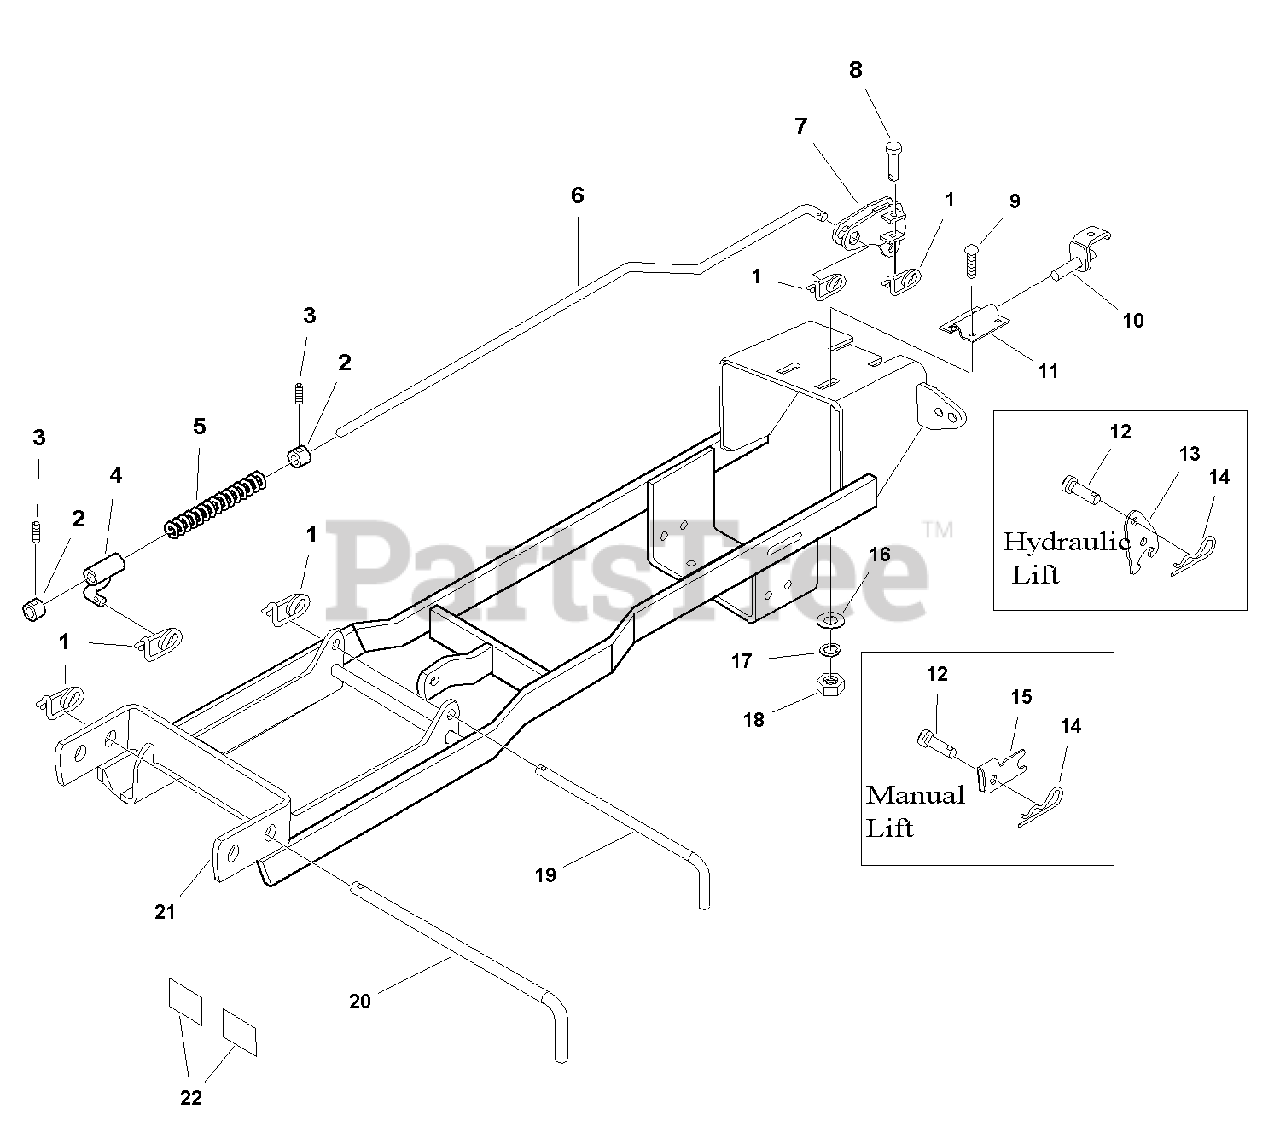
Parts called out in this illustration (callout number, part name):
1	RETAINER, Pin
2	COLLAR, Set
3	SCREW, Set, Square Head, Cup Point, 5/16-18 x 1/2, GR 8
4	TUBE & PIN ASSEMBLY
5	SPRING, Compression
6	ROD, Rear Lift
7	LEVER ASSEMBLY
8	PIN, Round Head,3/8 x 2-3/8
9	CARRIAGE BOLT, 5/16-18 x 1
10	SHAFT & HOOK ASSEMBLY
11	CLAMP, Wheel Support
12	PIN, Flat Head
13	PLATE, Presser Lock
14	CLIP, Hair Pin
15	PLATE, Pressure Lock
16	WASHER
17	LOCKWASHER, Spring, 5/16
18	NUT, Hex, 5/16-18
21	PUSH BAR ASSEMBLY
22	REFLECTOR, Red
